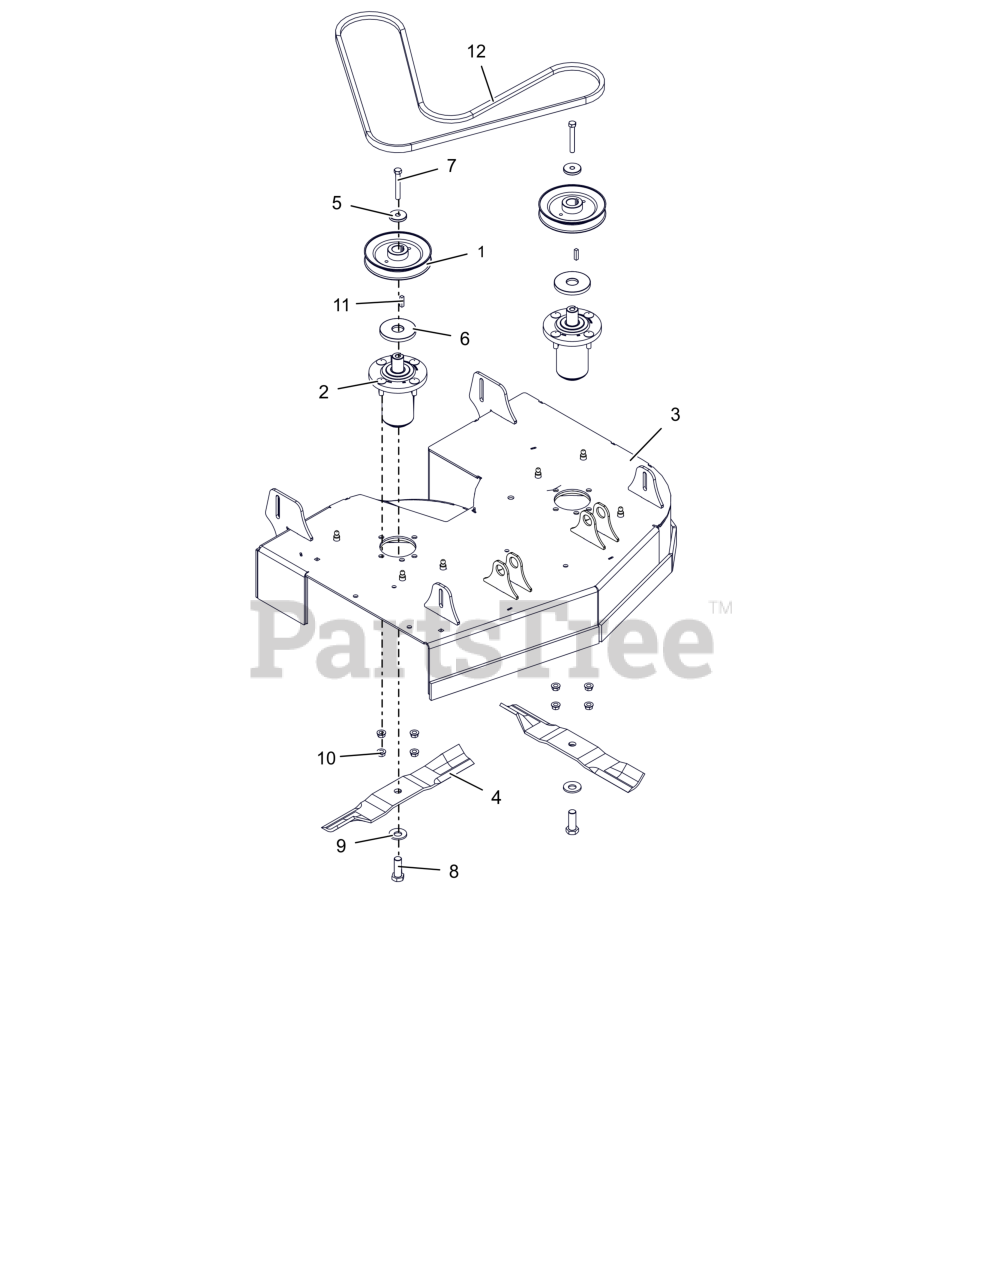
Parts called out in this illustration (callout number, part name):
1	PULLEY, V - 1.000 ID X 5.750 OD
2	ASM, ALUM SPINDLE
3	WLDMT, DECK 32" (ORANGE)
4	BLADE, 16.19" MOWER (HI-LIFT)
5	RETAINER, SHEAVE
6	SPCR- SHEAVE SPINDLE
7	BLT, HEX .38-16X2.75 G8 ZCC
8	BLT, HEX .62-18X1.75 G8 ZCC
9	WSHR-BLVL .669X1.535X.138
10	NUT-LK-CTR-FLG .375-16 GF ZCC
11	KEY, SQ .25X.25X1.00 RC 40-50
12	V-BELT, HB SECTION 80.04
